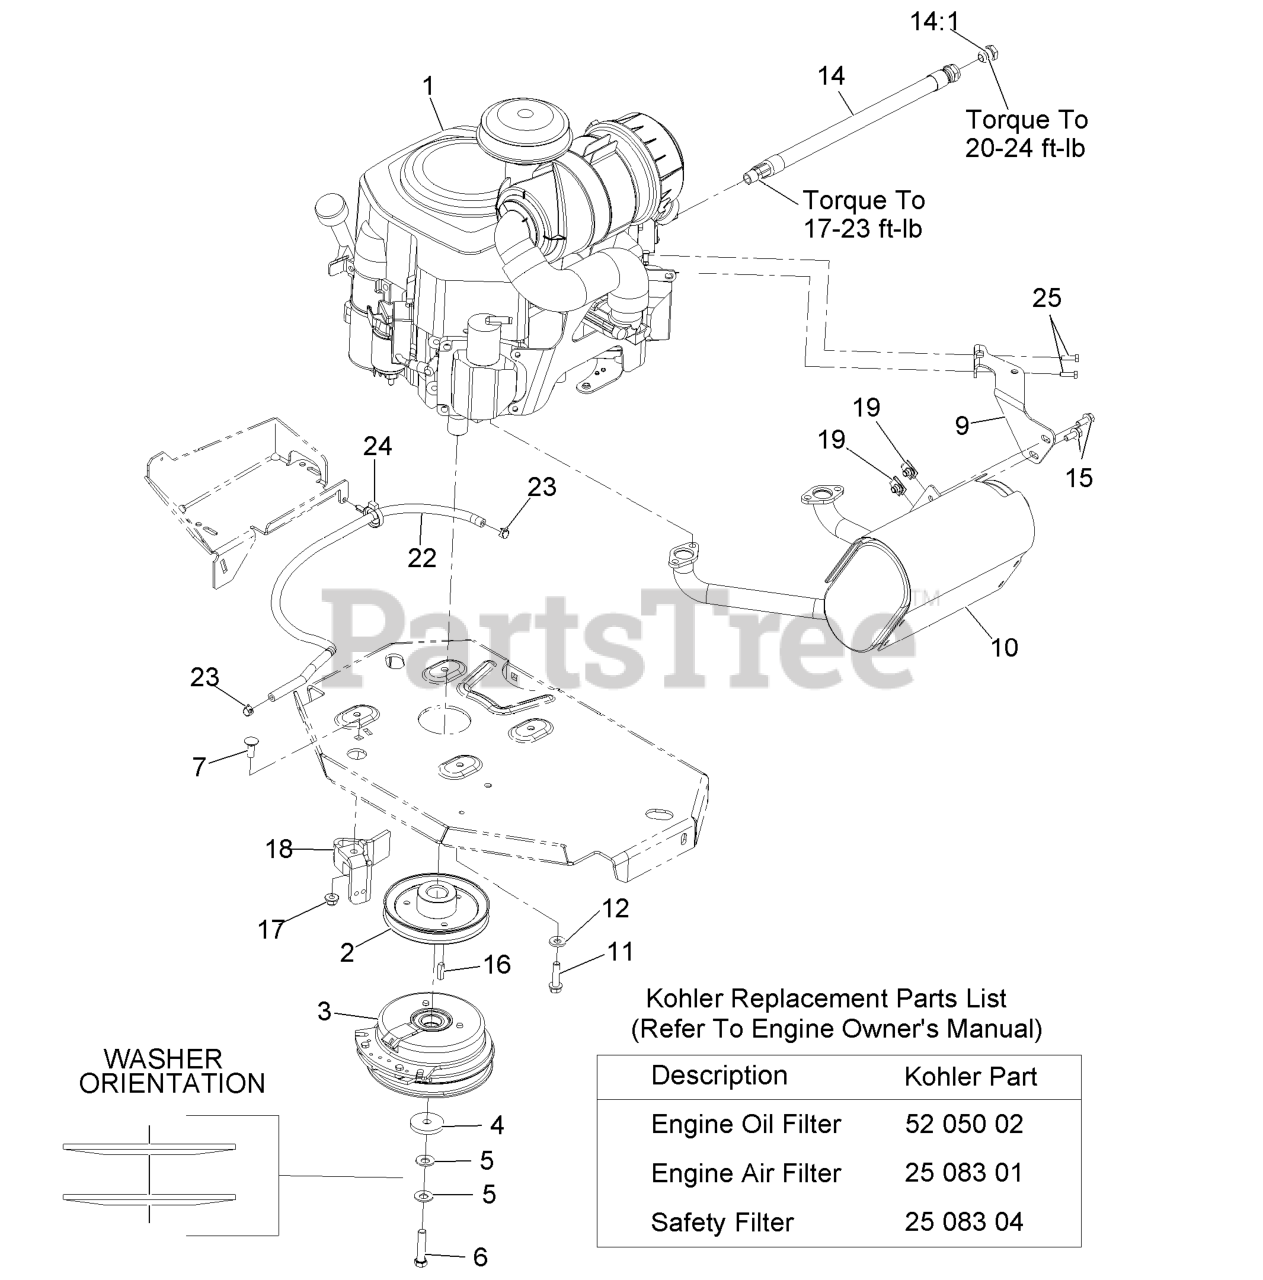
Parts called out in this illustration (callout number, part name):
1	Engine,Koh 27hp Hd
2	SHEAVE
3	CLUTCH KIT
4	WASHER-CLUTCH
5	WASHER-SPRING
6	SCREW-HH W/LOCTITE
7	SCREW-CARR
9	MUFFLER BRACKET KIT
11	SCREW-HWH
12	WASHER-BELLEVILLE
15	SCREW-HHF
17	NUT-HF, NI
18	CLUTCH-ANCHOR
22	HOSE-FUEL
23	CLAMP-HOSE
24	CLAMP-HOSE
25	SCREW-HH M6-1 X 20Mm W/Patch
